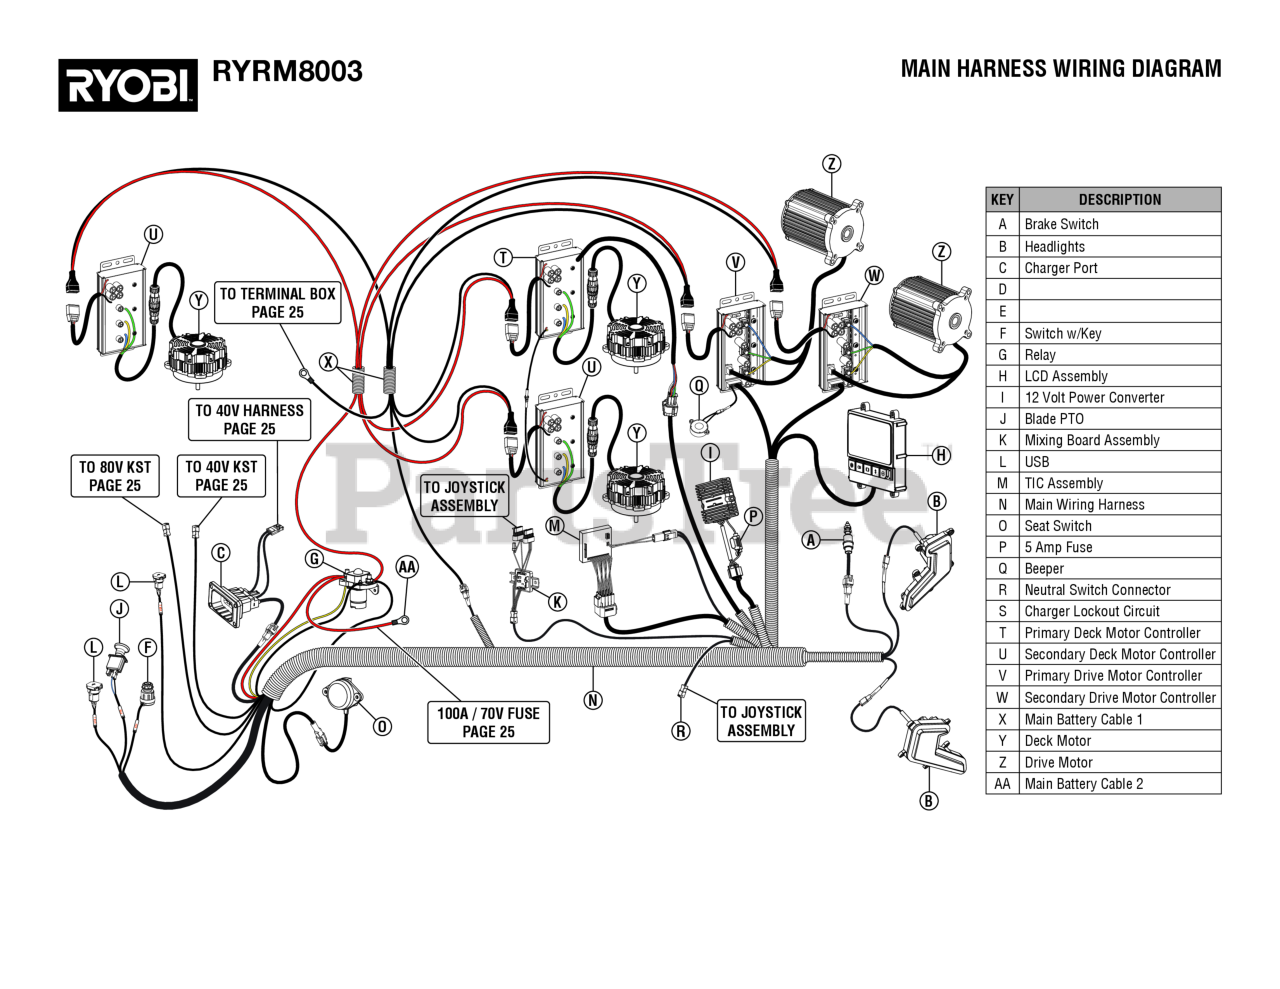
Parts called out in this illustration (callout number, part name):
A	Brake Switch
B	Headlights
C	Charger Port
D	Motor and Pump Assembly
E	Motor and Pump Assembly
F	Switch w/Key
G	Relay
H	LCD Assembly
I	12 Volt Power Converter
J	Blade PTO
K	Mixing Board Assembly
L	USB
M	TIC Assembly
N	Main Wiring Harness
O	Seat Switch
P	5 Amp Fuse
Q	Beeper
R	Neutral Switch Connector
S	Charger Lockout Circuit
T	Primary Deck Motor Controller
U	Secondary Deck Motor Controller
V	Primary Drive Motor Controller
W	Secondary Drive Motor Controller
Y	Deck Motor
Z	Drive Motor
